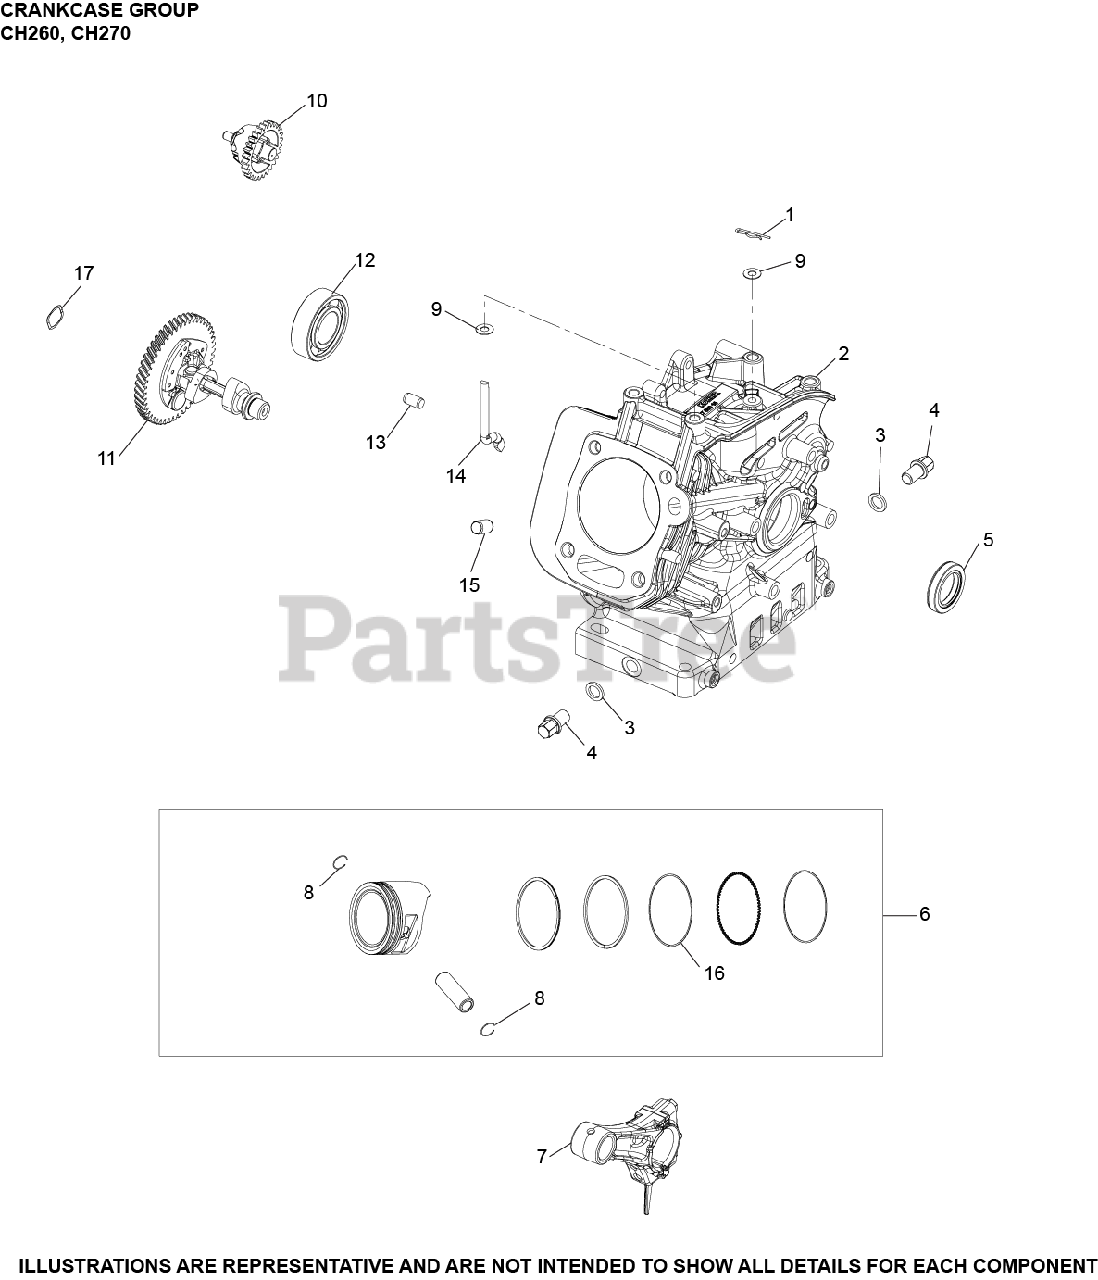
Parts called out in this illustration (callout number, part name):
3	WASHER, DRAIN PLUG - (#1846801S)
4	KIT, DRAIN PLUG
5	SEAL, OIL - USE 17 032 30-S
6	KIT, PISTON USE 17 874 10-S
6	KIT, PISTON (0.25 O.S.)
7	ROD, CONNECTING ASSEMBLY
8	RETAINER, PISTON PIN
9	WASHER, FLAT (13MM OD)
10	GOVERNOR ASSEMBLY USE 17 310 08-S
11	CAMSHAFT ASSEMBLY
12	BEARING, BALL
13	PIN, DOWEL
14	SHAFT, GOVERNOR CROSS
15	DOWEL, CYLINDER HEAD-(#1438013S)
16	RING SET, PISTON
16	RING SET
16	RING SET (0.25 O.S.)
